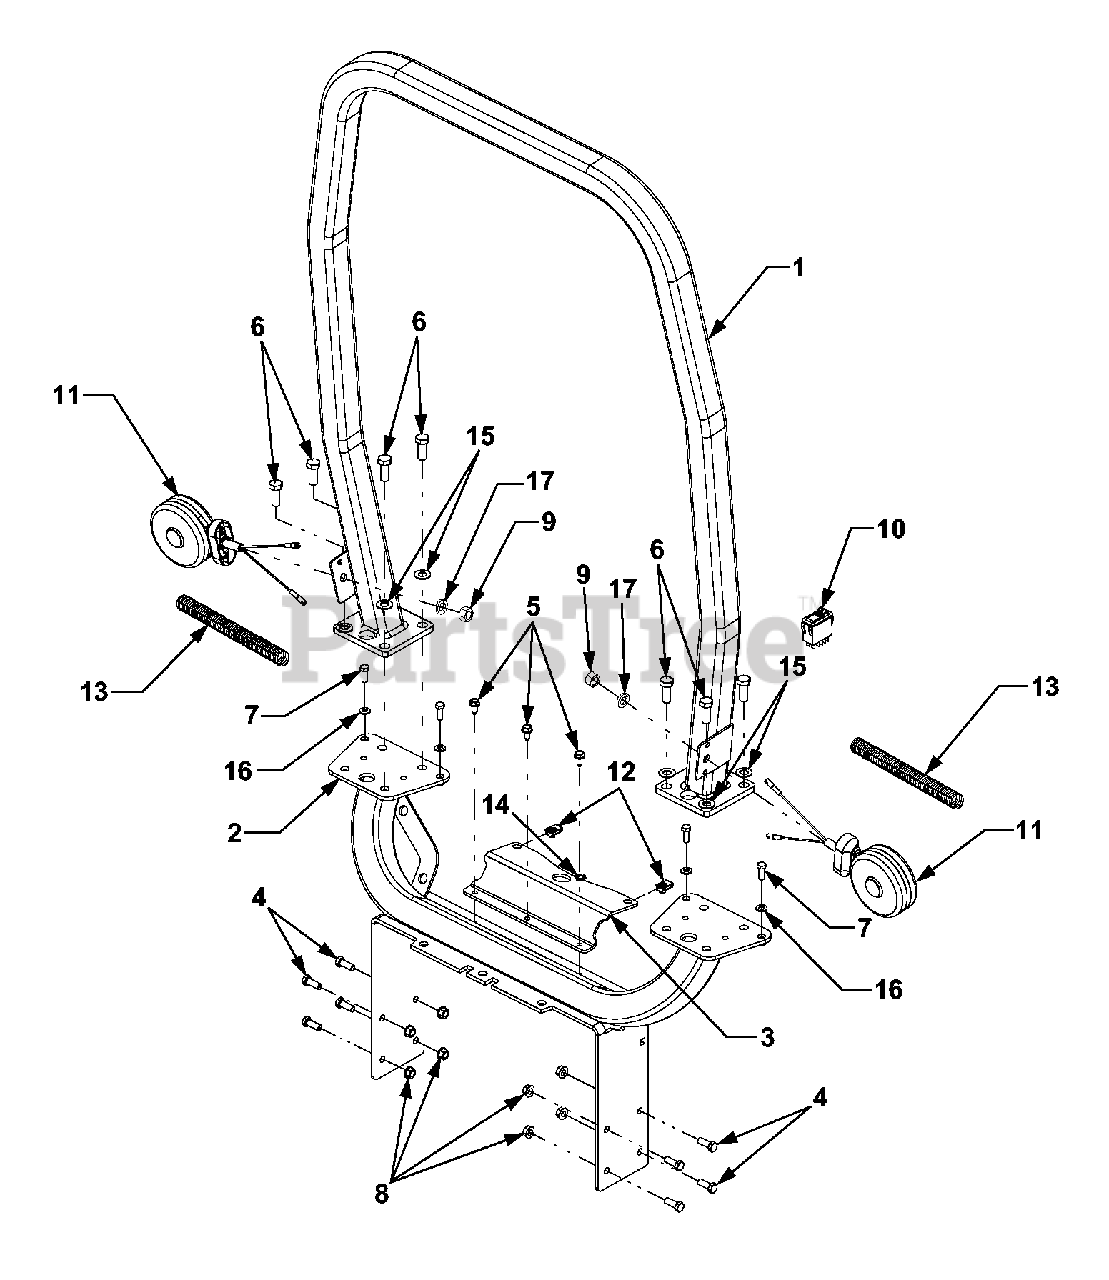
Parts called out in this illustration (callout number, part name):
3	Bracket, Rear Seat Mounting
4	Screw, Hex Cap, 3/8-16 x 1.0 GR5
5	Screw, Hex Wash. Hd. Tapp 5/16-18 x .75
6	Screw, Hex Cap, 1/2-13 x 1.25 GR5
7	Screw, Hex Cap, 5/16-18 x .875 GR5
8	Nut, Hex Flange Lock, 3/8-16 GRF
9	Nut, Hex, 1/2-20 GR5
10	Switch, Hazard
11	Light, Hazard
12	Nut, Speed, 5/16-18
13	Conduit, 6"
14	Washer, Ext. Tooth Lock, 3/8
15	Washer, Flat, .51 x 1.0 x .060
16	Washer, Flat, .344 x .688 x .065
17	Washer, Lock, 1/2
